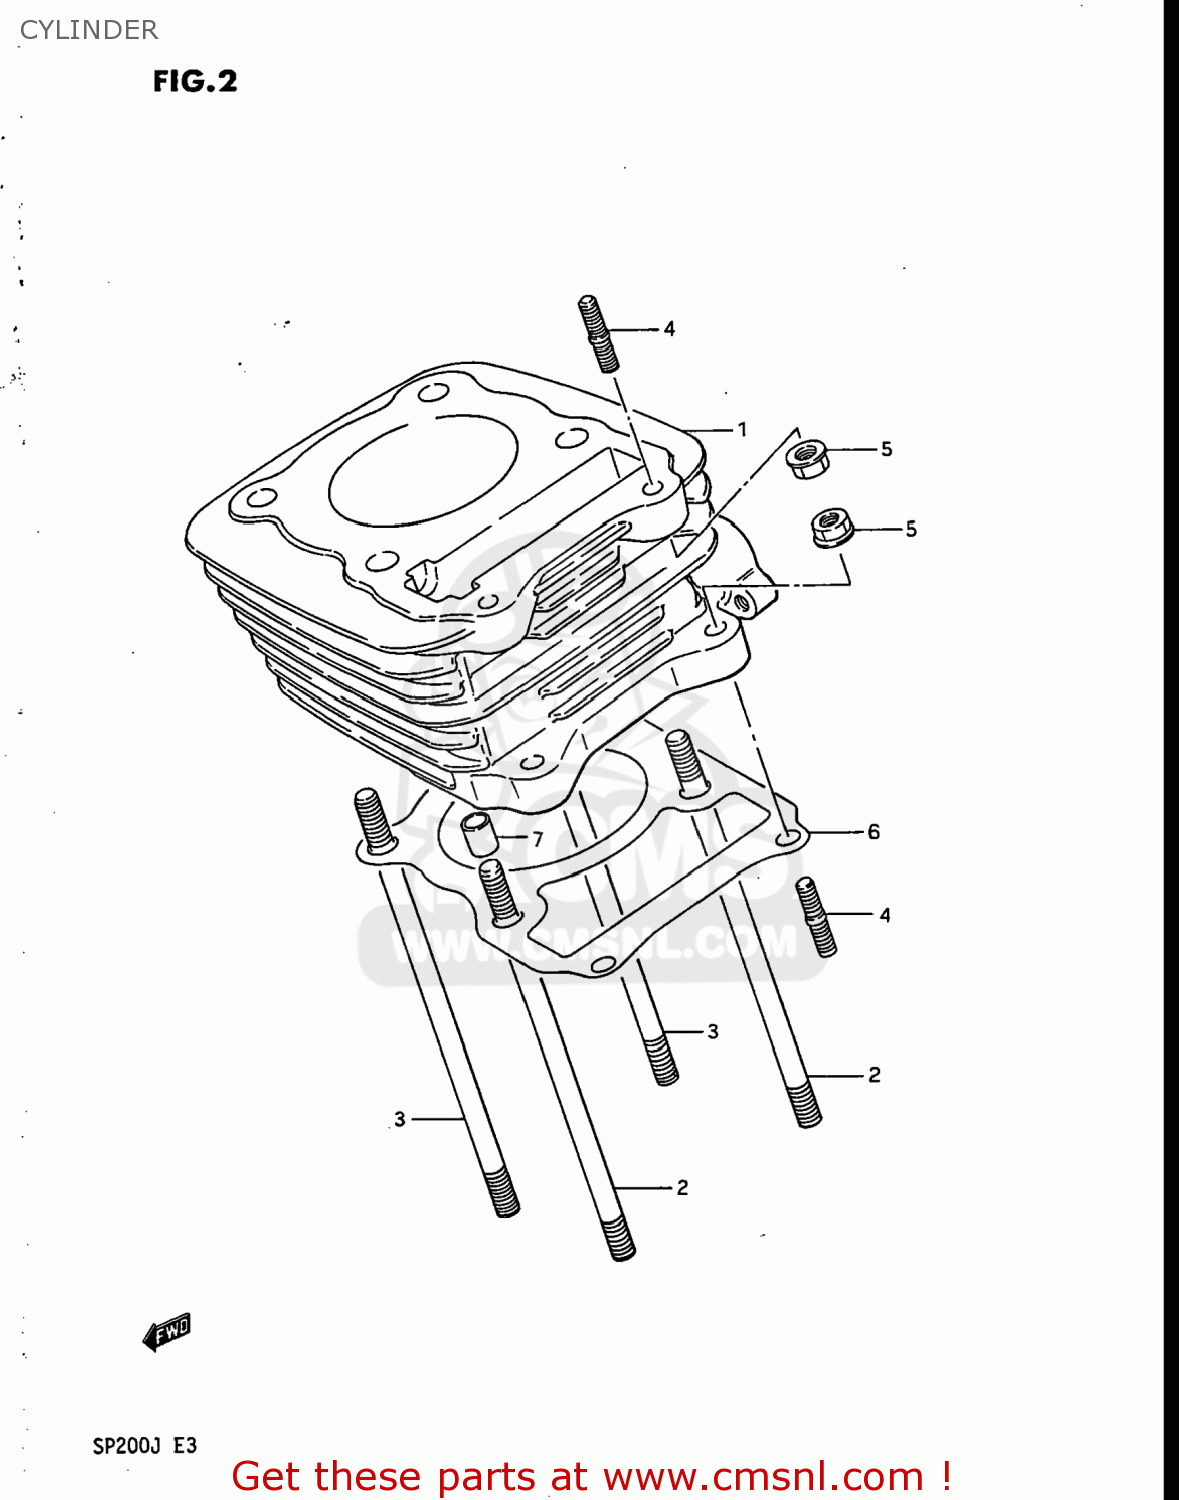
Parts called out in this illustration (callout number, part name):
1	CYLINDER
2	BOLT,STUD
3	BOLT,STUD(8X167)
4	STUD 6X25
5	NUT 6MM
6	GASKET,CYLINDER (MCA)
7	PIN
